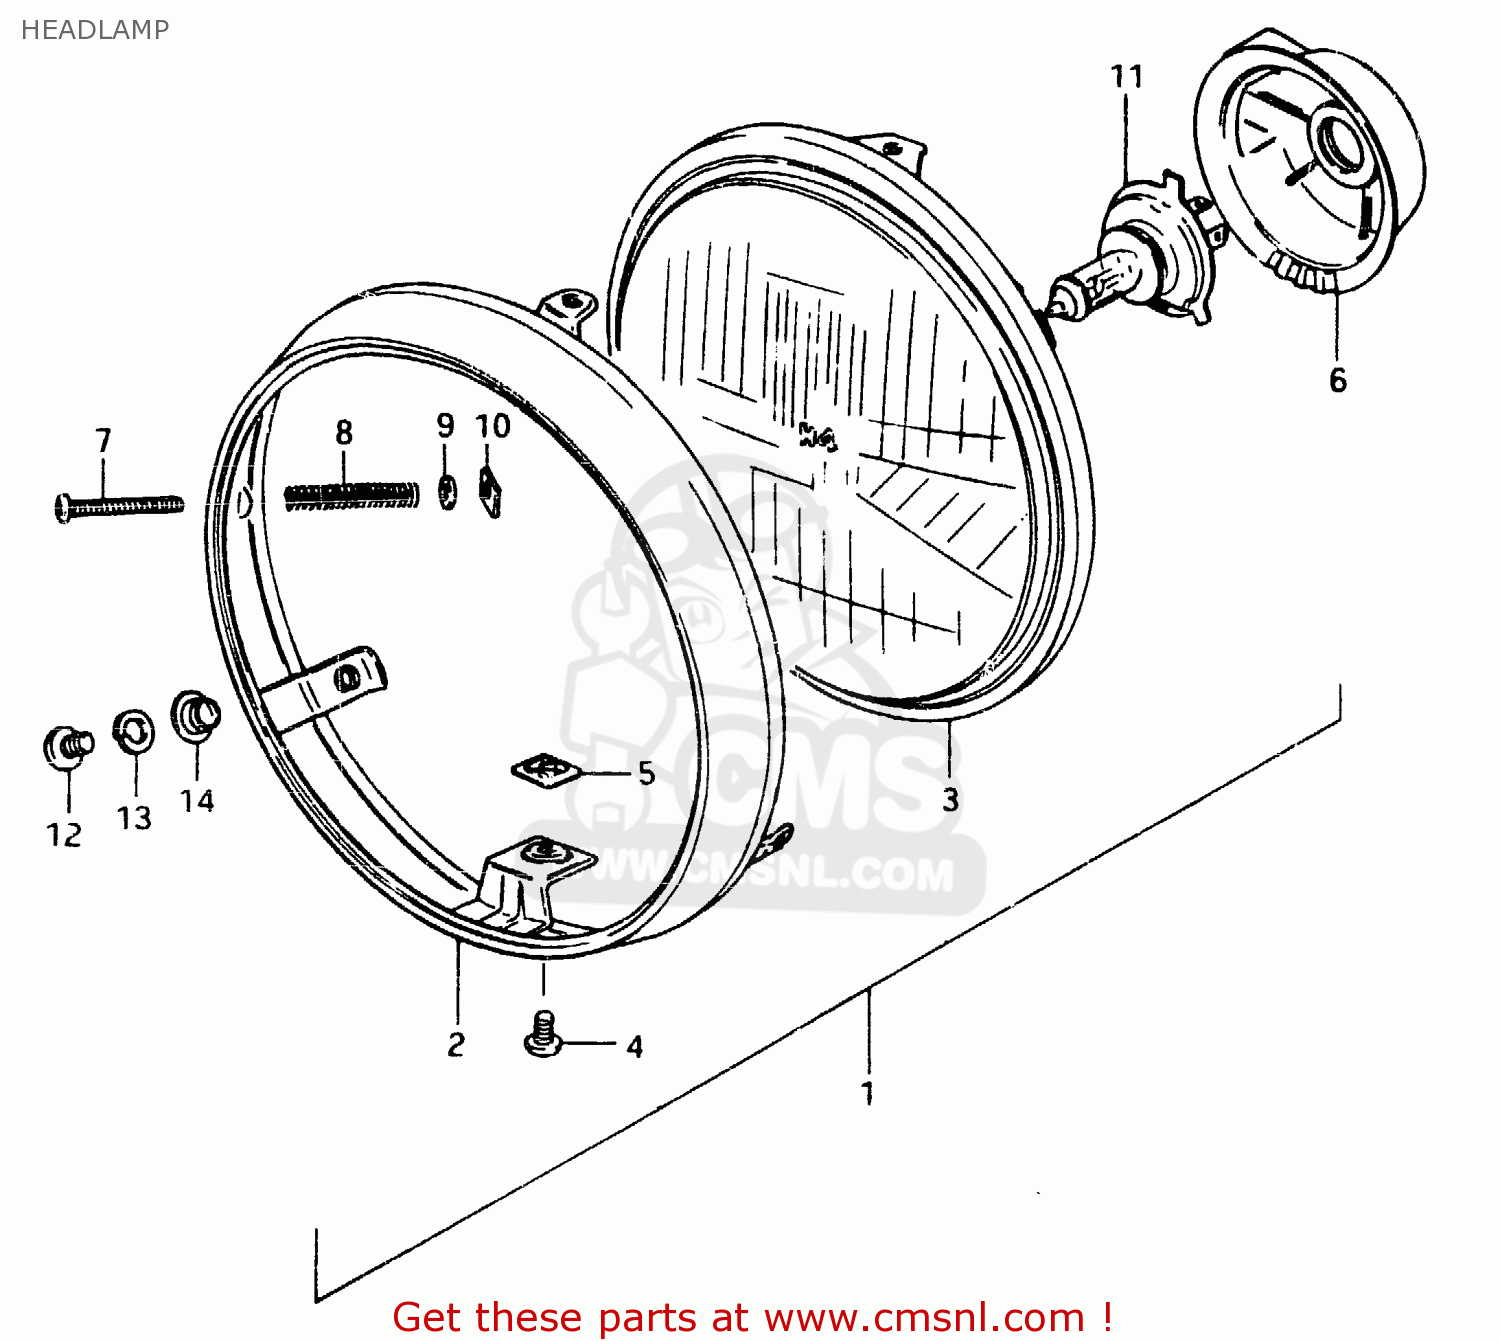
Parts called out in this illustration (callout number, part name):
1	HEADLAMP ASSEMBLY
2	RIM
3	LAMP UNIT
4	SCREW
5	NUT,ADJUSTING
6	COVER,SOCKET
7	SCREW,HEADLAMP ADJUST
8	SPRING
9	WASHER
10	NUT,HEADLAMP ADJUSTER
11	BULB(12V60/55W,H4)
12	SCREW
13	WASHER,LOCK
14	WASHER
